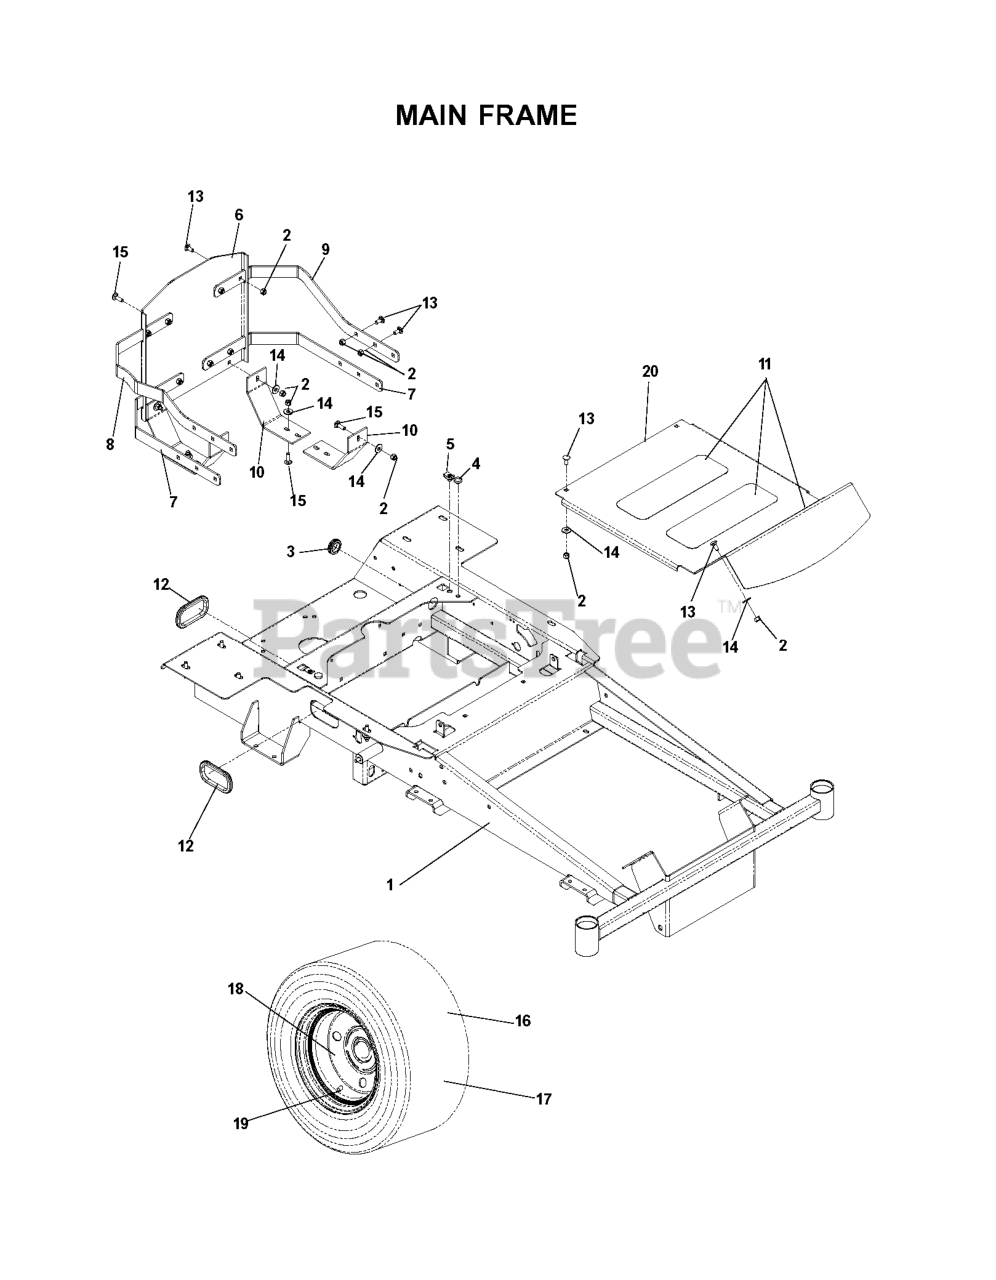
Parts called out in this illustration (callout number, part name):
1	FRAME W/DECALS #
2	NUT 5/16 NYLOC
3	RUBBER GROMMET
4	GROMMET, BUMPER
5	U-CLIP 5/16-18 NUT RETAINER
6	ENGINE GUARD
7	REAR GUARD STRAP, LOWER
8	REAR GUARD STRAP, UPPER RIGHT
9	REAR GUARD STRAP, UPPER LEFT
10	SKID PLATE
11	ANTI-SKID PAD
13	BOLT 5/16C X 3/4" CARRIAGE
14	WASHER 5/16 FLAT
15	RHSNB 5/16C X 1
16	TIRE/WHEEL ASM 18X9.5-8
17	TIRE 18 X 9.5 TURF RIDER
18	RIM.8X7.W/8".OFFSET.SILVER.ZTR
19	VALVE STEM TR-412
